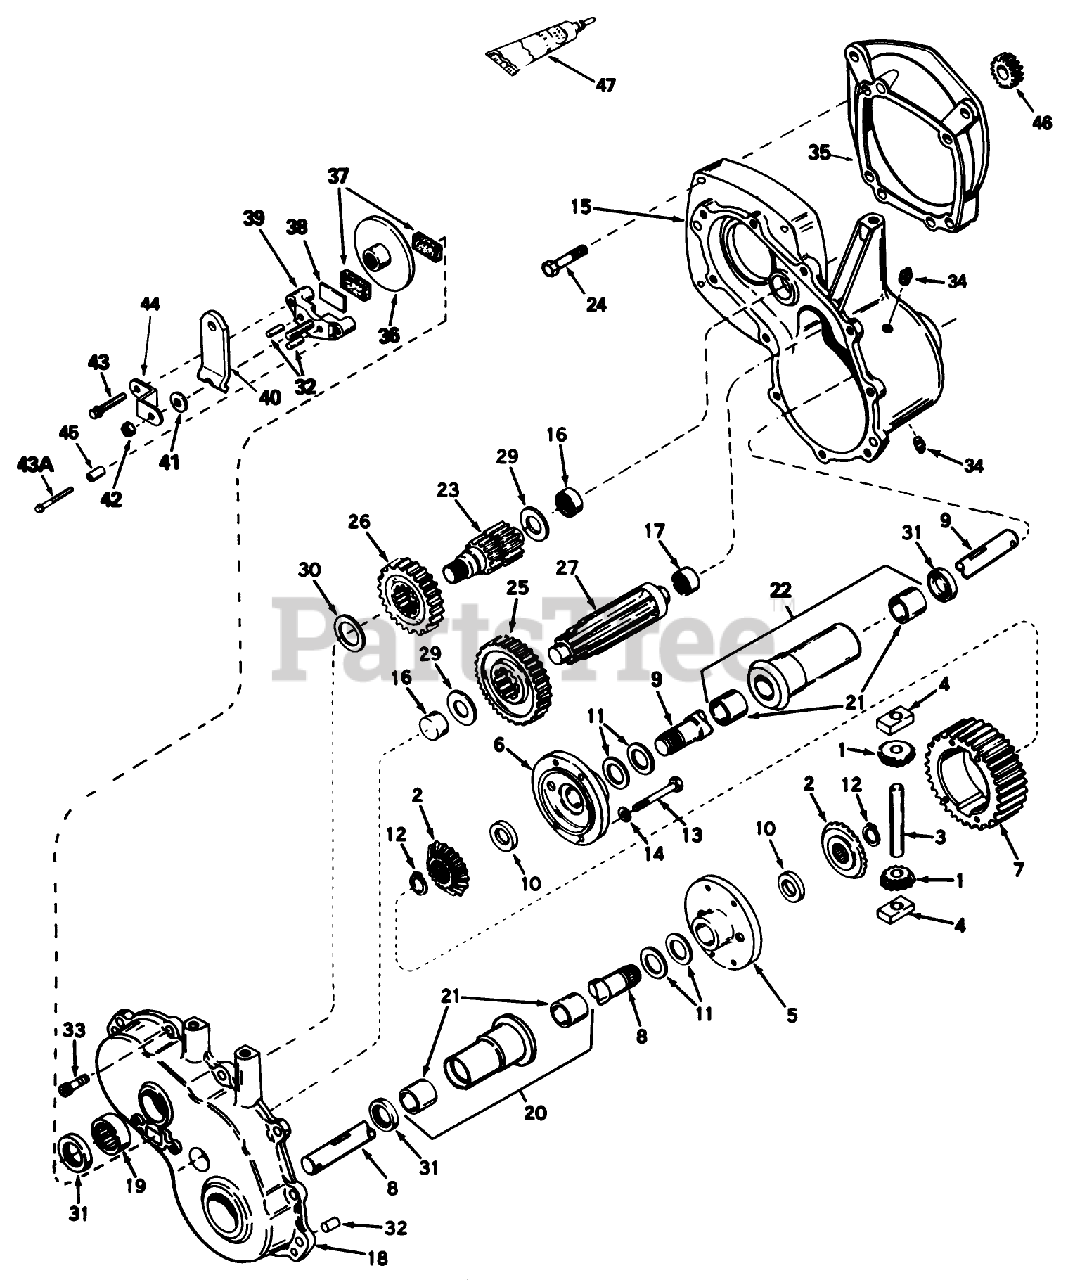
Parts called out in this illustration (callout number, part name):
1	Pinion-Bevel
2	Gear-Bevel
3	Pin-Drive
4	Biock-Drive
5	Carrier-Differential
6	Carrier-Differential
7	Gear-Ring
8	Axle 16-5/8"
9	Axle-21-57/64"
10	Washer
11	Washer
12	Ring-Snap
13	Screw-Hex Hd.
14	Lockwasher
15	Case Assy. (Incl. Ref. #16 8 17)
16	Bearing
17	Bearing-Needle
18	Cover Assy. (Incl. Ref. #16 & 19)
19	Bearing Needle
20	A Housing & Bushing Assembly (6-5/8" long) (Incl. 2 of No. 21)
21	Bushing
22	Housing & Bushing Assembly (8-5/8" long) (Incl. 2 of No. 21)
23	Shaft-Brake
24	Screw-Hex Hd.
25	Gear-Output
26	Gear-Spur
27	Shaft-Output
29	Washer
30	Washer
31	Seal-Oil
32	Dowel Pin
33	Screw-Thread Forming
35	Plate-Adapter
36	Disc-Brake
37	Brake Pad
38	Brake Pad Plate
39	Nozzle-Carburetor
40	Lever-Brake
41	Washer
42	Locknut
43	Ring Set (.020 O S)
43A	Screw-Hex. Flange
44	Bracket
45	Spacer
46	Gear-Spur 22T
47	Gasket Eliminator
